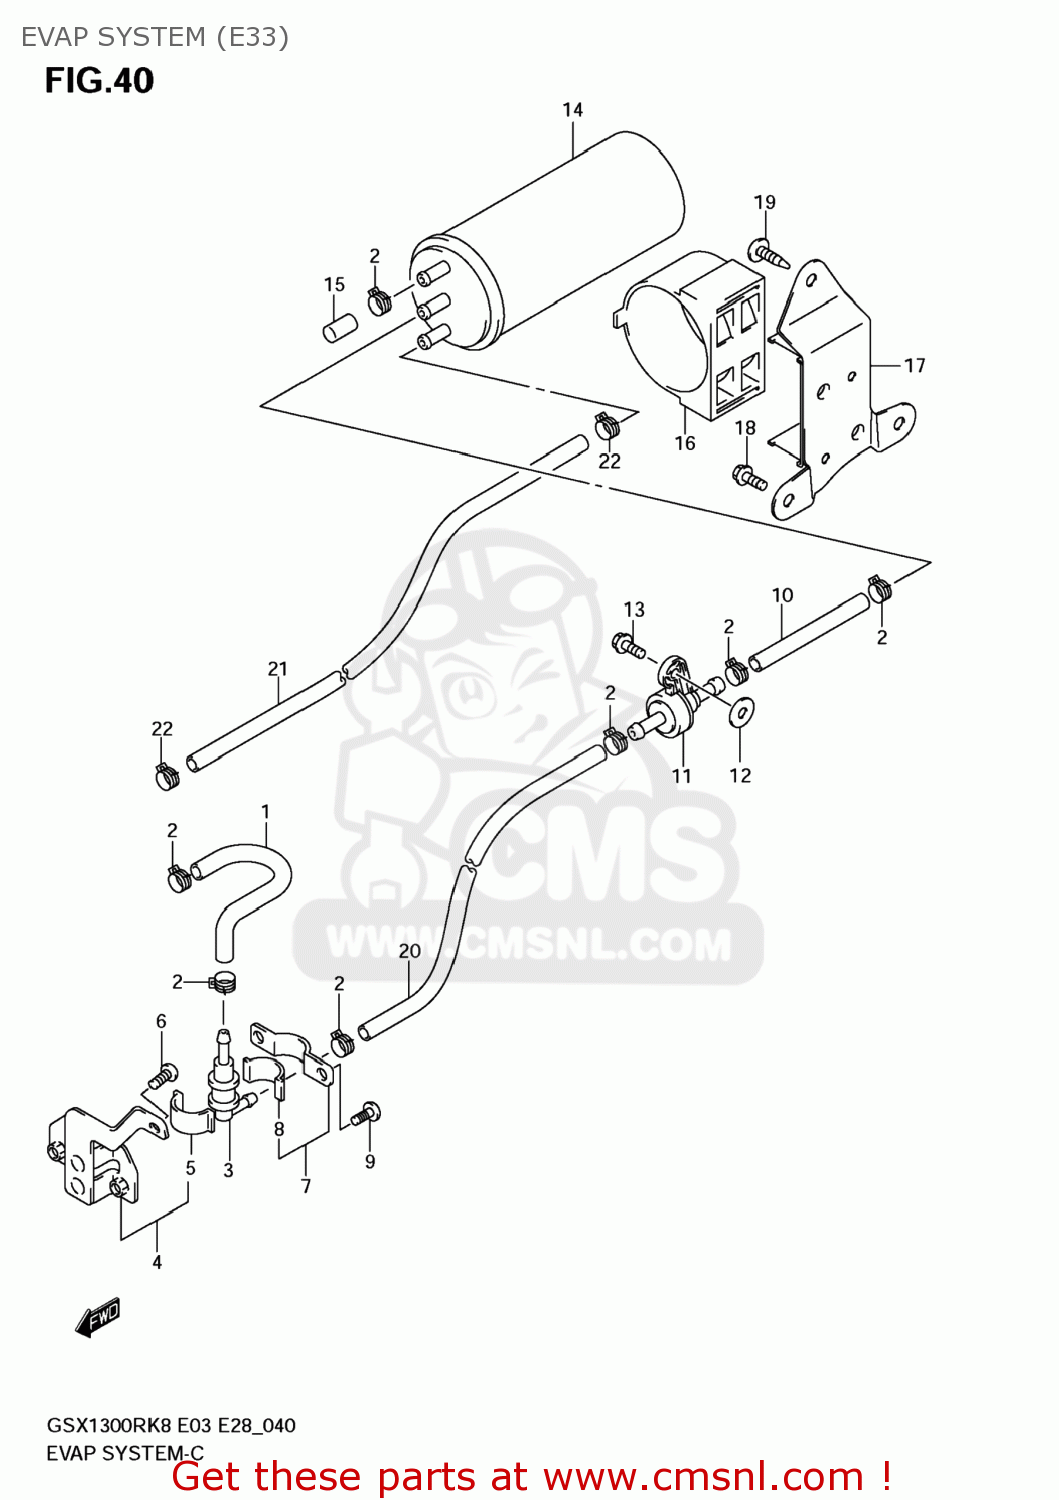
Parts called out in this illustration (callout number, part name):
1	HOSE,TANK & BREATHER VALVE
2	CLIP
3	VALVE,FUEL TANK BREATHER
4	PLATE,TANK BREATHER VALVE
5	CUSHION
6	SCREW
7	PLATE,FUEL TANK BREATHER NO.2
8	CUSHION
9	SCREW
10	HOSE,2 WAY & B
11	VALVE,2 WAY & BREATHER VALVE
12	WASHER(6.5X20X1.2)
13	BOLT
14	CANISTER ASSY,CHARCOAL
15	CAP,OD:11.5
16	CUSHION,CANISTER
17	BRACKET,CANISTER
18	BOLT
19	SCREW
20	HOSE,CANISTER
21	HOSE
22	CLIP
